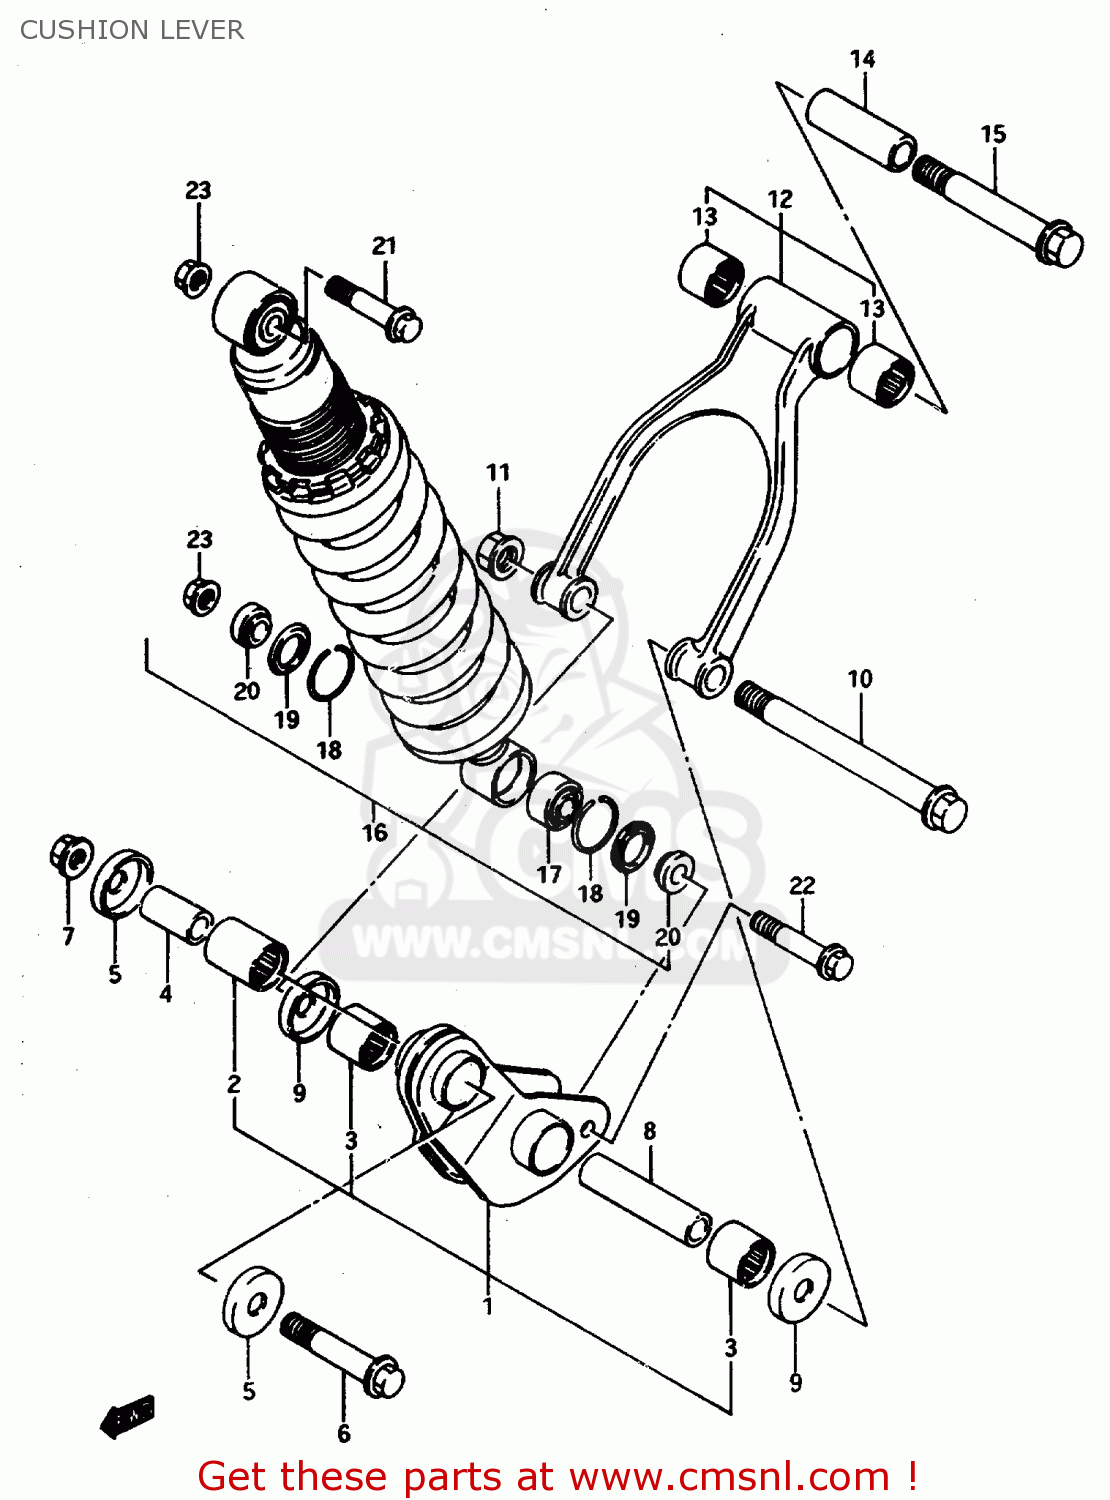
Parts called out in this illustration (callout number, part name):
1	LEVER SET, REAR CUSHION
2	BEARING(20X27X30)
3	BEARING(20X27X23.5)
4	SPACER,RR CUSHION LEVER FR
5	SEAL,RR CUSHION LEVER FR DUST
6	BOLT,RR CUSHION LEVER FR
7	NUT 12MM
8	SPACER (14X20X78)
9	SEAL,RR CUSHION LEVER CTR DUST
10	BOLT,RR CUSHION ROD LWR
11	NUT
12	ROD SET,REAR CUSHION,LEFT
13	BEARING(20X27X23.5)
14	SPACER (14X20X63)
15	BOLT,RR CUSHION ROD UPR
16	ABSORBER ASSY,RR SHOCK
17	BEARING,RR CUSHION LEVER
18	RING,STOPPER
19	SEAL,DUST RR SHOCK ABSORBER
20	COLLAR
21	BOLT(10X50)
22	BOLT(10X54)
23	NUT
